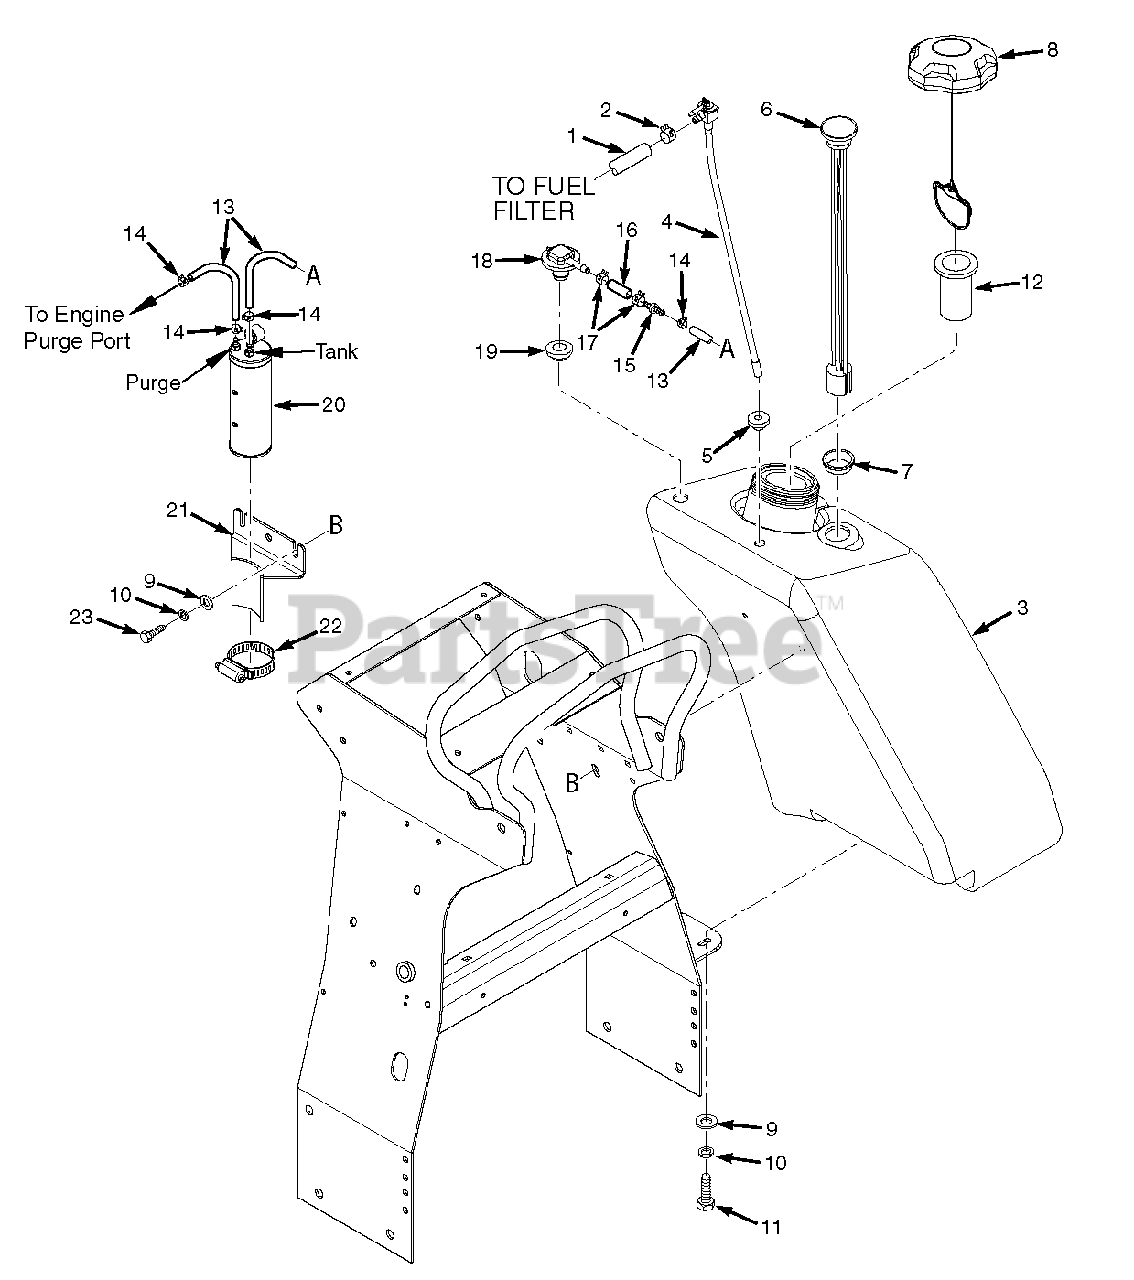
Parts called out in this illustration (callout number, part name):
1	Fuel Hose, 1/4" ID
2	Clamp, Fuel Hose
3	Fuel Tank Assembly - SVR-36A / SVR-48V
3	Fuel Tank Assembly - SVR-52V / SVR-61V
4	Valve, Fuel Shut Off
5	Bushing, .56 Dia. Viton
6	Fuel Gauge Assembly
7	Seal, Fuel Gauge
8	Fuel Cap, Tethered (E.P.A.)
9	Flatwasher, 5/16-.375 x .875 x .083
10	Lockwasher, 5/16" Spring
11	Bolt, Hex Head 5/16-18 x 3/4"
12	Tube, Fuel Tank Insert - 4"
13	Hose, Vapor Recovery 3/16"
14	Clamp, Vapor Recovery Hose
15	Mender, 1/4 x 3/16 w/.02 Hole
16	Hose, Vapor Recovery 1/4"
17	Clamp, Fuel Hose 7/32" ID
18	Fitting, Remote Vent
19	Grommet, Viton
20	Carbon Canister - SVR-36A / SVR-48V
20	Carbon Canister - SVR-52V / SVR-61V
21	Canister Mounting Bracket, SVR
23	Bolt, Hex Head 5/16-18 x 1"
